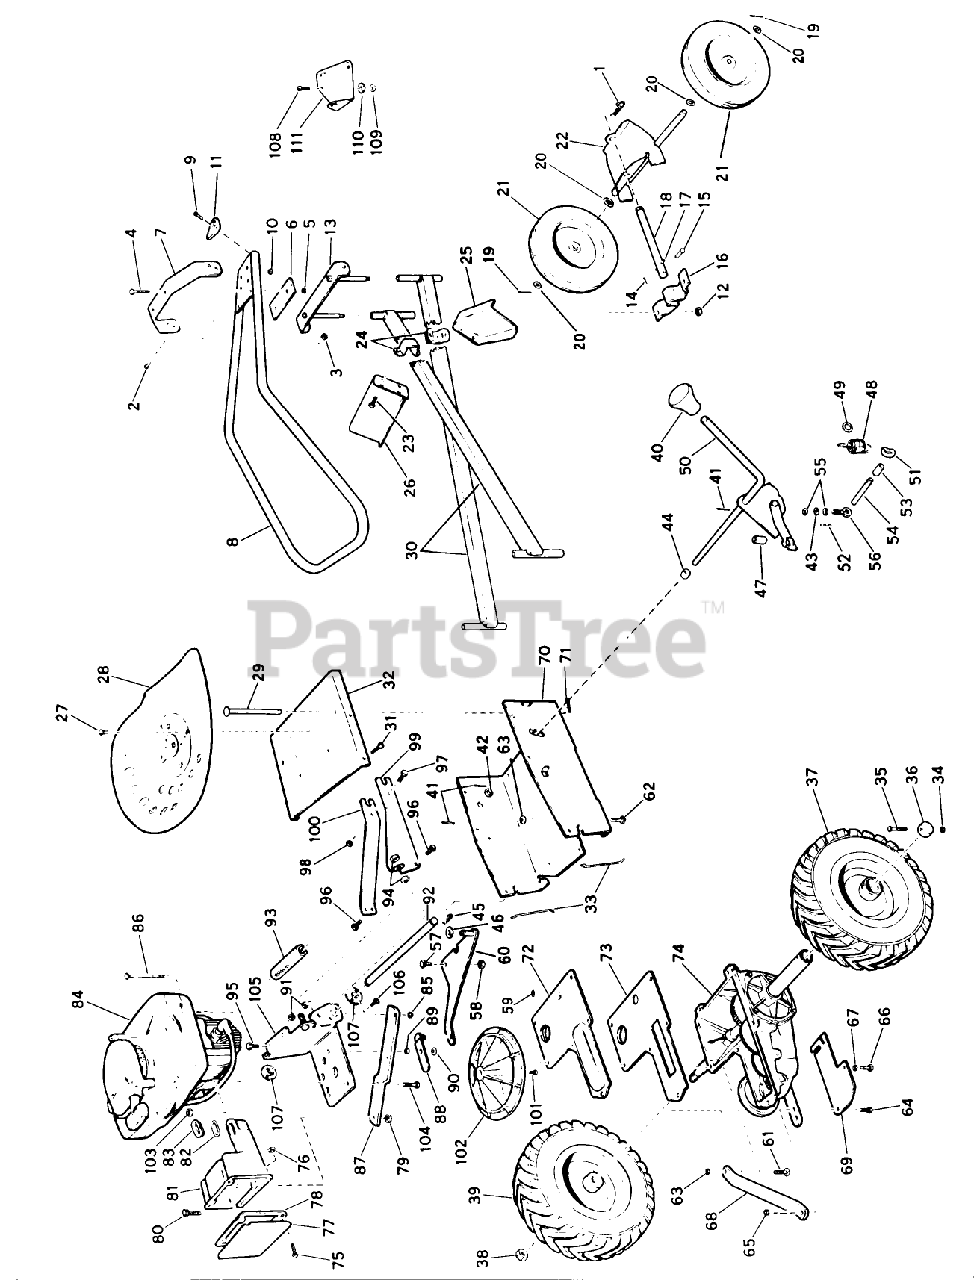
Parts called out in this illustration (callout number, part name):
2	Bolt-Handle
3	STOP NUT
5	STOP NUT
6	Clamp-Handle Pivot Bracket
7	Bracket-Handle Pivot
10	STOP NUT
14	Cotter Pin
16	Pivot Bracket-Frame, Bottom
24	Bracket-Foot Pedal Clamp
27	Screw-Seat to Cover
32	Cover-Shroud
35	Screw-Differential
43	WASHER, LOCK
44	Roller-Speed Control
48	Spring-Clutch
56	Bolt-Eye, Ramp Pin Adjustment
59	Felt-Vent
61	Screw-Shroud
66	Screw-Guard to Housing
70	Shroud-Frame
72	Plate-Transmission
74	Transmission Assembly
79	Nut-Huglok
85	LOCKNUT E
92	Shaft-Engine Mounting Plate
98	STOP NUT
99	Arm-Clutch
107	Bearing-Engine Mounting
109	STOP NUT
